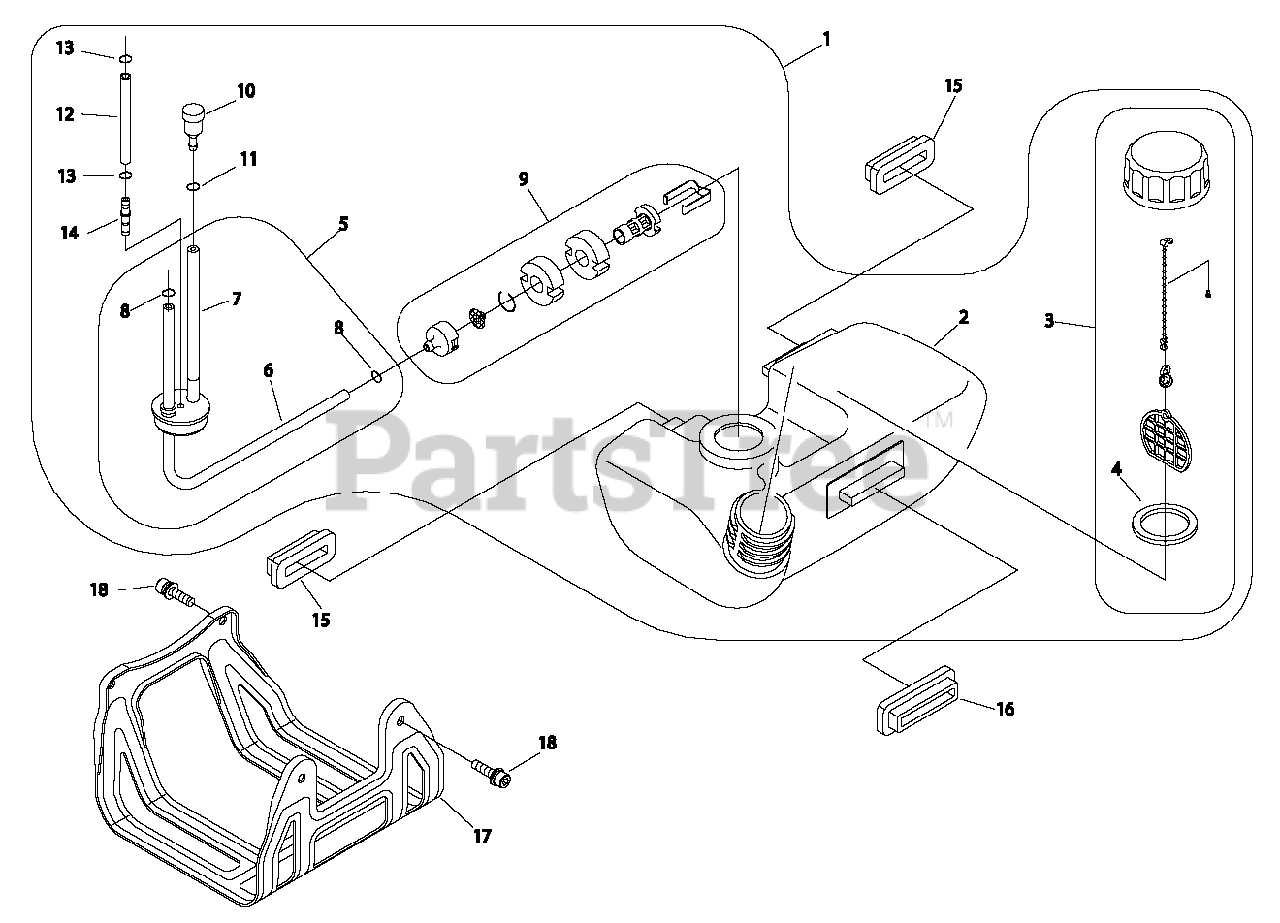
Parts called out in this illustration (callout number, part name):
1	TANK ASSY, FUEL
2	TANK, FUEL
3	CAP ASSY, FUEL
4	GASKET, FUEL CAP
5	PIPE ASSY, FUEL
6	PIPE, FUEL 3.3×6×215
7	GROMMET
8	CLIP Ø6
9	FILTER ASSY, FUEL
10	VENT ASSY
11	CLIP Ø6
12	PIPE, FUEL RETURN
13	CLIP Ø6
14	CONNECTOR, PIPE
15	CUSHION, FUEL TANK
16	CUSHION, FUEL TANK
17	GUARD, FUEL TANK
18	BOLT M5×16
